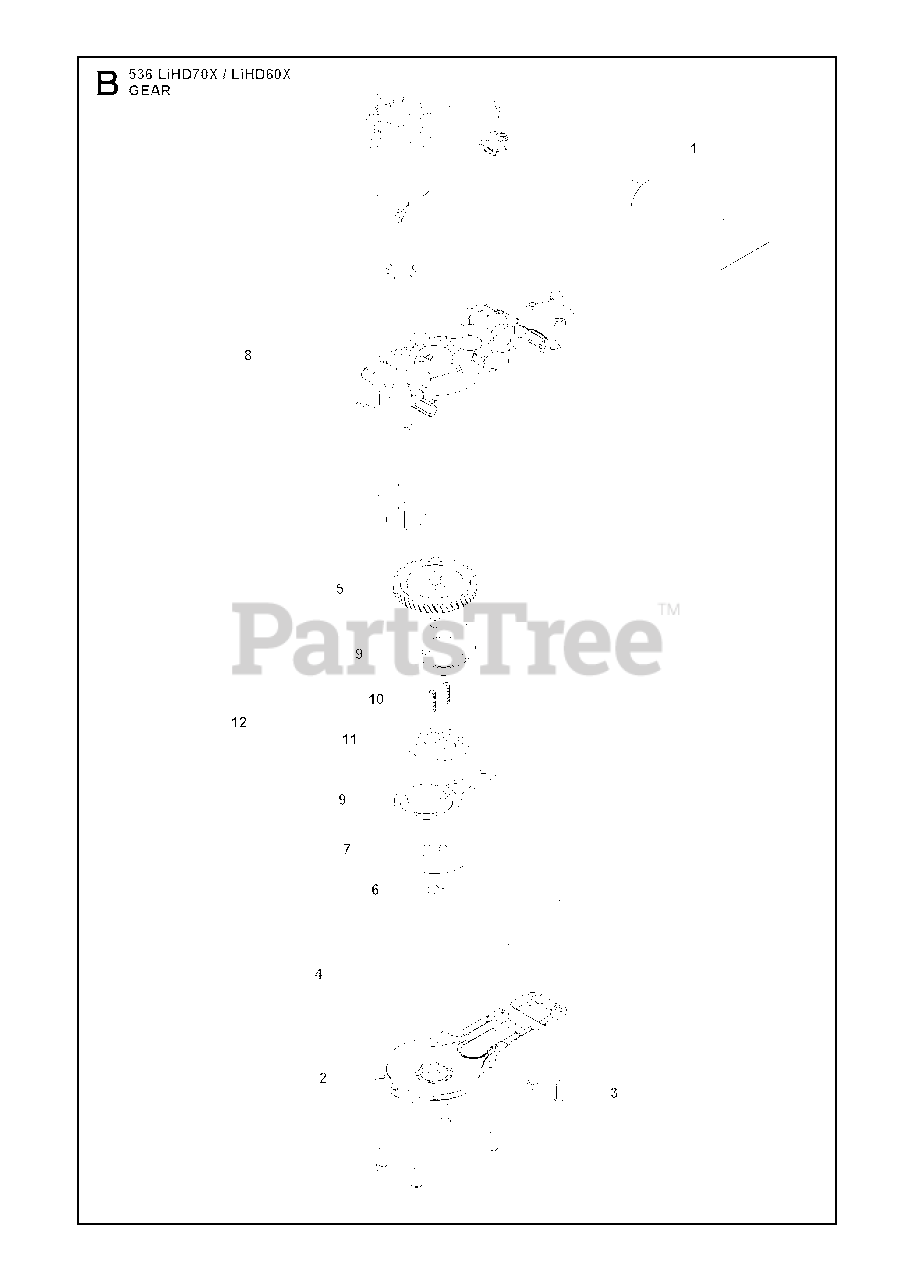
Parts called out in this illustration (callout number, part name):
1	GREASE 20G HEDGE TRIM
2	BOTTOM PLATE ASSEMBLY
3	SCREW IHSCFT
5	HELICAL GEAR CPL DC
6	LOCK WASHER
7	WASHER DISK DISC
8	MOTOR ASSY MOTOR-GEARBOX ASSY
9	CONNECTING ROD ASSY
10	HEAVY DUTY DOWEL PIN PROJEKT 1
11	ECCENTRIC DISC
12	GEAR HELICAL KIT 536LIHD60X/ 5
